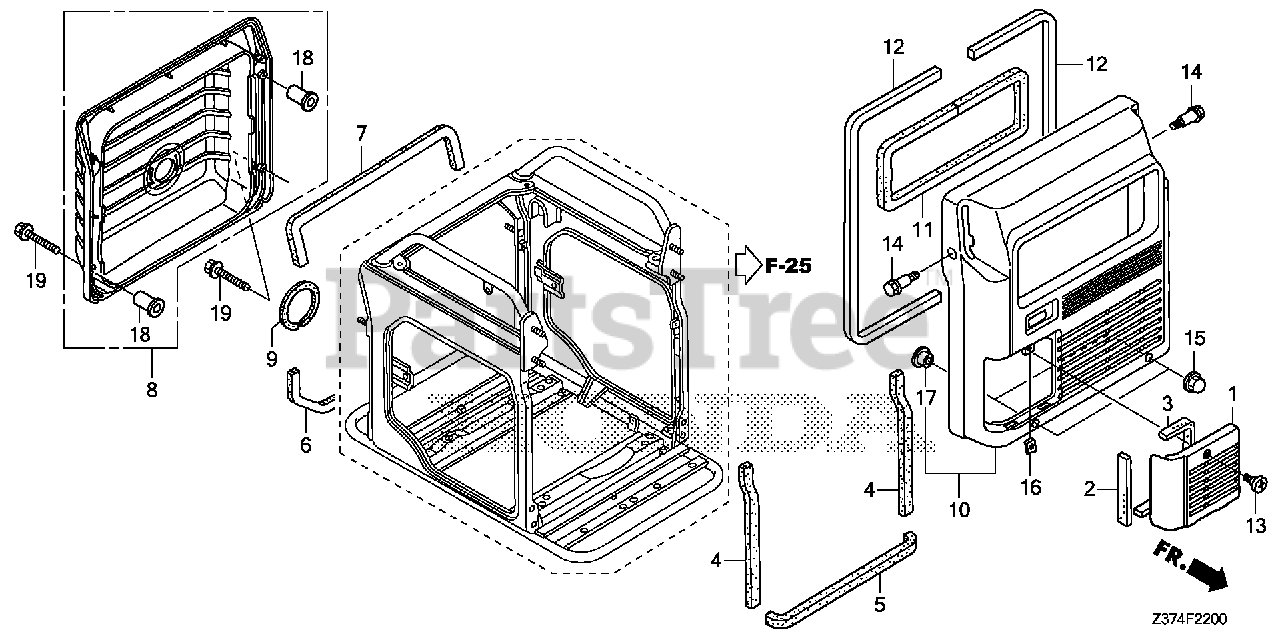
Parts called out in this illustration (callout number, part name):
1	COVER, MAINTENANCE *NH314* (CONDUCT GRAY)
2	SEAL A, MAINTENANCE COVER
3	SEAL B, MAINTENANCE COVER
4	SEAL (10X6X320)
5	SEAL (10X10X500)
6	SEAL, RR. (LOWER)
7	SEAL (10X5X640)
8	COVER, RR. *NH314* (CONDUCT GRAY)
9	SEAL (10X8X290)
10	COVER, FR. *NH314* (CONDUCT GRAY)
11	SEAL, CONTROL PANEL
12	SEAL A, FR. COVER
13	SCREW, SPECIAL (6X16)
14	BOLT, SPECIAL (6X26)
15	NUT, OPEN STAY (6MM)
16	NUT, SPRING (6MM)
17	COLLAR, FR. COVER
18	COLLAR, COVER
19	BOLT, FLANGE (6X30)
